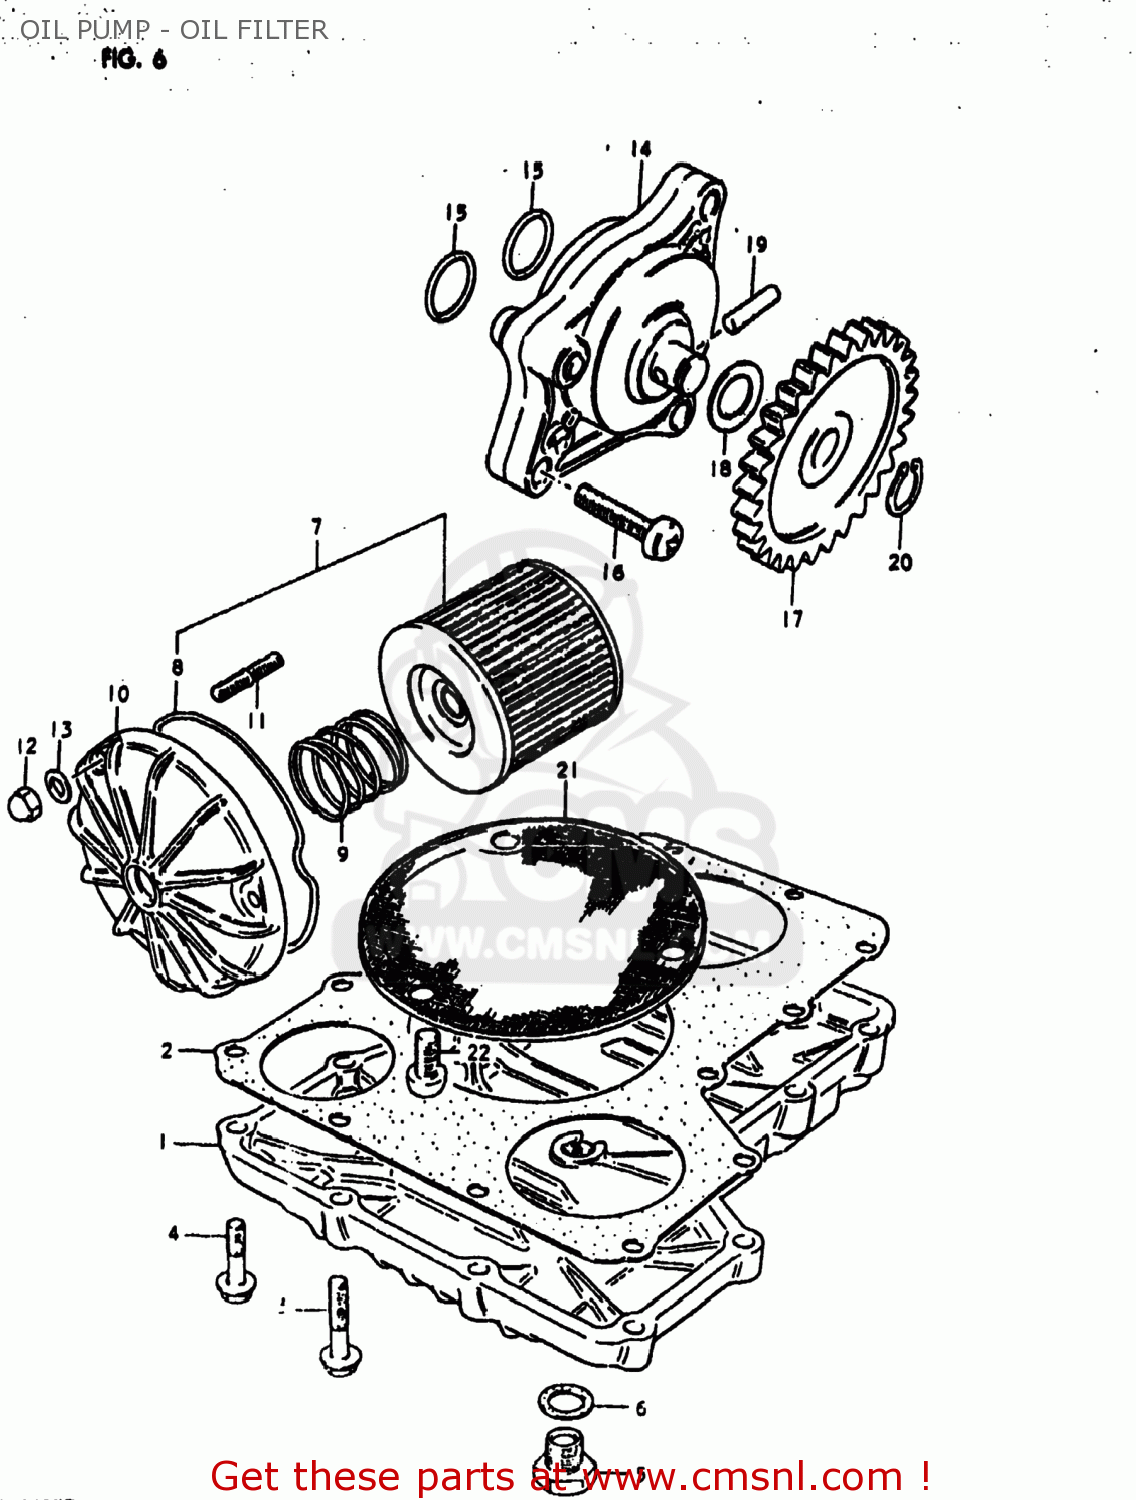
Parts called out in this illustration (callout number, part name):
1	PAN,OIL
2	GASKET,OIL PAN (MCA)
3	BOLT
4	BOLT
5	PLUG
6	GASKET(14X19.2X2) (NAS)
7	FILTER ASSY,ENGINE OIL
8	O RING,OIL FILTER CHAMBER CAP
9	SPRING
10	CAP,OIL FILTER
11	STUD 6X20
12	NUT
13	WASHER
14	PUMP ASSEMBLY,OIL
15	O RING(D:1.9,ID:13)
16	SCREW
17	GEAR,OIL PUMP DRIVEN
18	SHIM
19	PIN(4X15.8)
20	CIRCLIP
21	STRAINER,ENGINE OIL
22	SCREW 6X12
